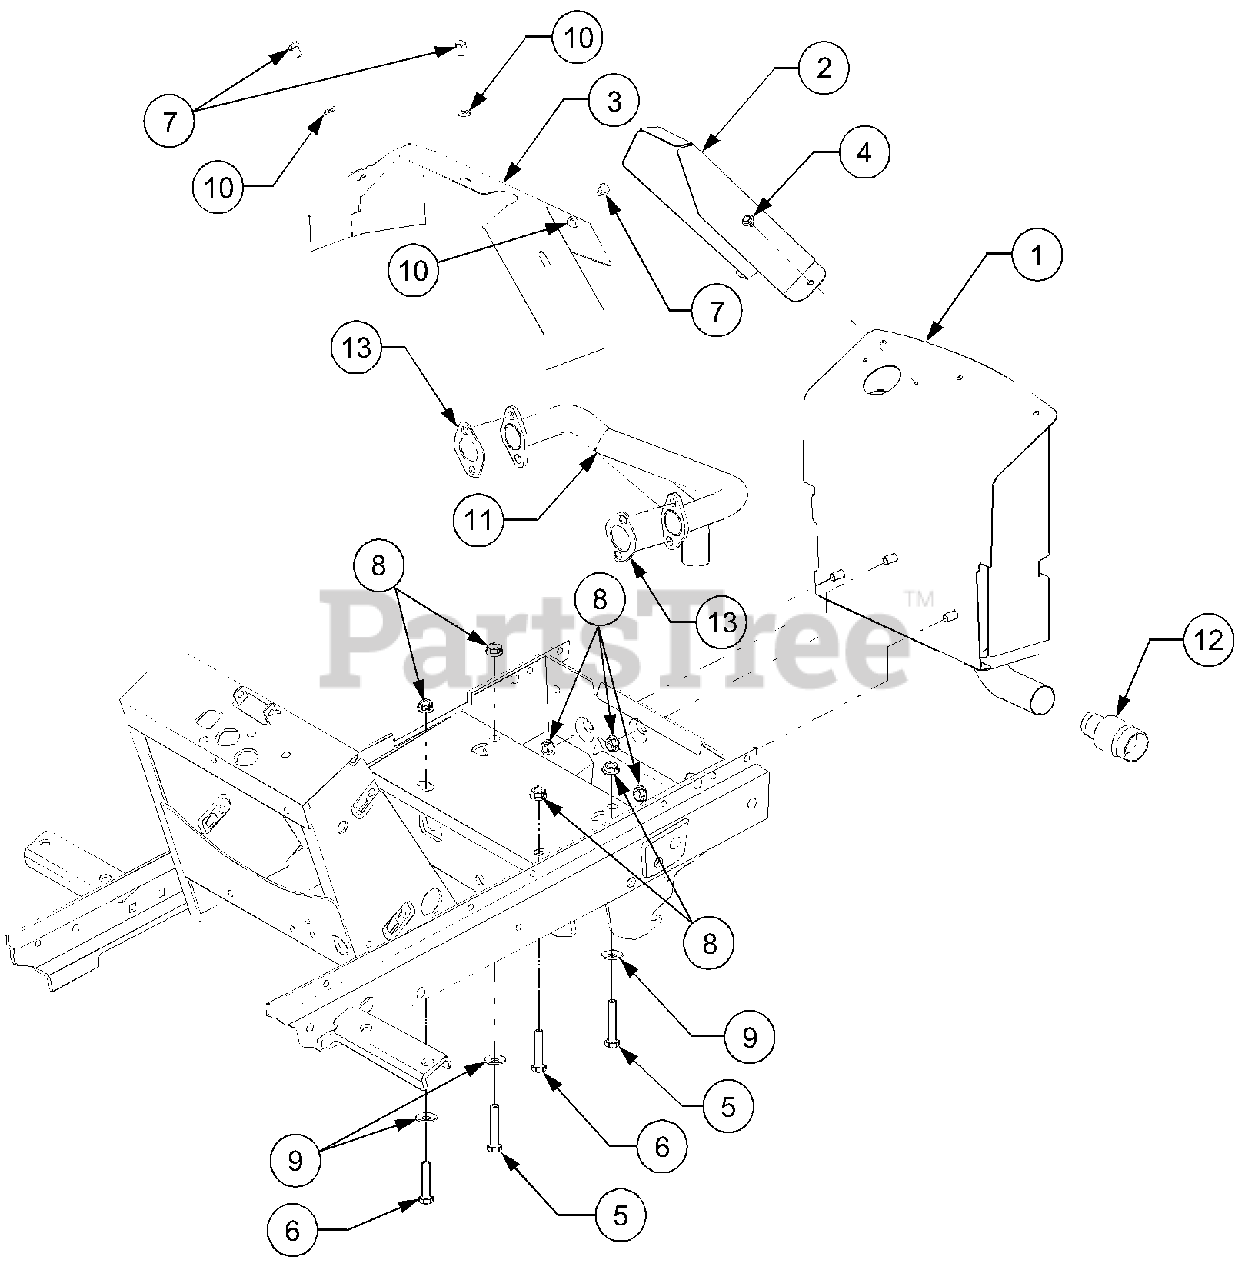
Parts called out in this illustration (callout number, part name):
1	Muffler Assembly
2	Sheild, Muffler Tube
3	Sheild, Engine Heat
4	Screw, Hex Wsh Hd Tap, #10-16 x .38
5	Bolt, Eng Mount, 5/16-18 x 1.75 GR5
6	Screw, Hex Cap, 5/16-18 x 1.5 GR5
7	Screw, Hex Cap, M6-1.0 x 10 GR8.8
8	Nut, Hex Flange Lock, 5/16-18
9	Washer, Bell, .345 x .88 x .060
10	Washer, Flat, .281 x .5 x .063
11	Tube, Exhaust
12	Arrestor, Spark
13	Gasket, Exhaust
